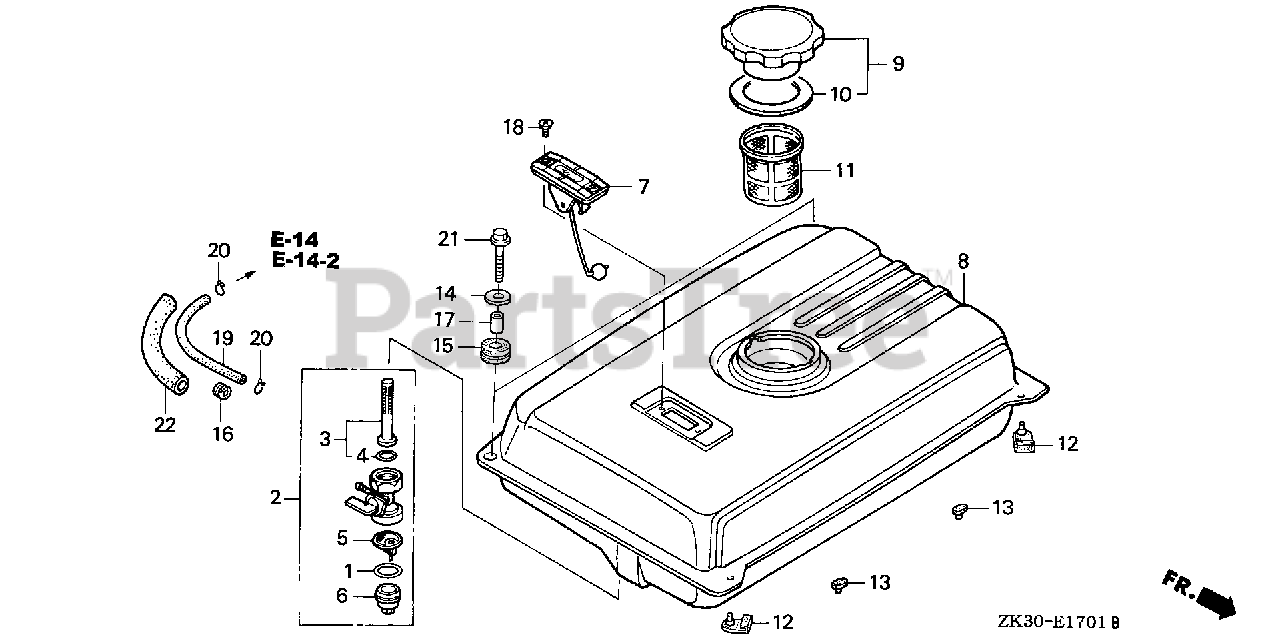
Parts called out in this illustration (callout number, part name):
1	GASKET, FUEL STRAINER CUP
2	PETCOCK ASSY.
3	SCREEN SET, FUEL STRAINER
4	O-RING (9.0X1.3)
5	FILTER, CUP
6	CUP, FUEL STRAINER
16	RUBBER, FUEL (9X15X10)
19	BULK HOSE, FUEL (4.5X3000) (4.5X210)
20	CLIP, TUBE (B8)
